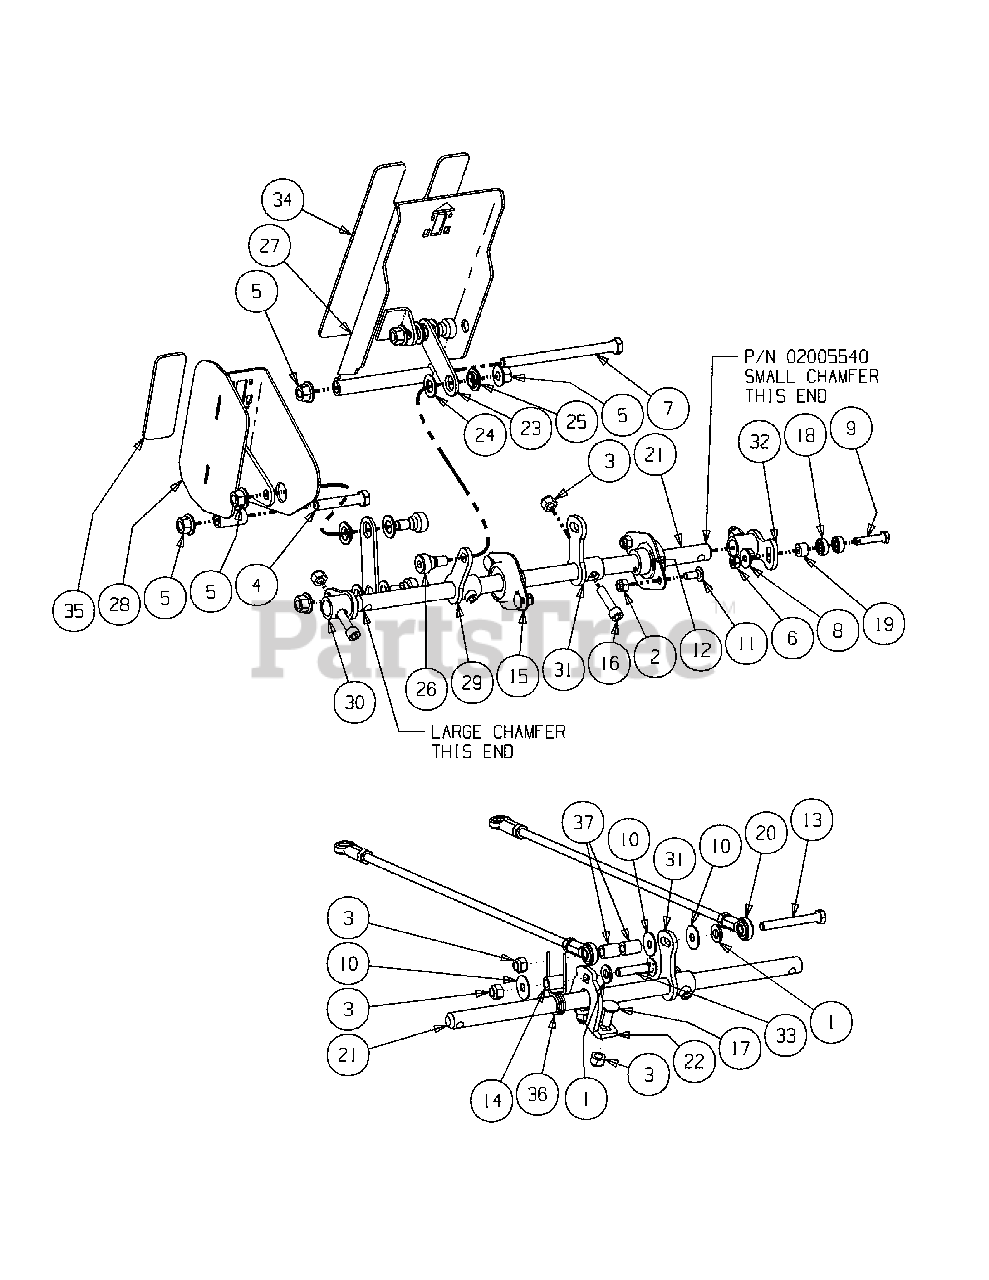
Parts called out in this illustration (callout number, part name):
1	Flat Washer, 5/16
2	Lock Nut w/Nylon Insert
3	Nut, 5/16-18, nylock
4	HHCS, 3/8-16 x 2.00
5	Flange Lock Hex Nut, 3/8-16
6	Lock Nut, 1/4-NC, Side
7	HHCS, 3/8-16 x 5.00
8	Washer, .265 x .75 x .062
9	HHCS, 1/4-20 x 1.25
10	Washer, .325 x .930 x .045
11	Carriage Screw, 1/4-20 x .62
12	Shaft Collar
13	HHCS, 5/16-18 x 2.5
14	Spacer, .315 ID x .500 OD x .699 LG
15	Flange Bearing
16	Socket Head Capscrew, 5/16-18 x 1.25
17	Carriage Bolt, 5/16-18 x .88
18	Ball Bearing, .25 ID x .625 OD x .196
19	Spacer, .256 x .500 x .330
20	Speed Control Rod Assembly
21	Shaft, .625 x 15.556
22	Retainer Bracket
23	Conrol Pedal Link
24	Washer, .51 x .88 x .06
25	Flange Bearing, .502 x .875 x .180
26	Shoulder Bolt, .50 x .25 x 3/8-16
27	Pedal Assembly, Forward
28	Pedal Assembly, Reverse
29	Arm Assembly, 1.75 LG x .625 Dia.
30	Arm Assembly, 1.375 LG x .625 Dia.
31	Arm Assembly, 1.75 LG x .625 Dia.
32	Hub Assembly
33	Carriage Bolt, 5/16-18 x 1.50
36	Torsion Spring, .66 ID x .47 LG
37	Spacer, .315 ID x .500 OD x .520 LG
